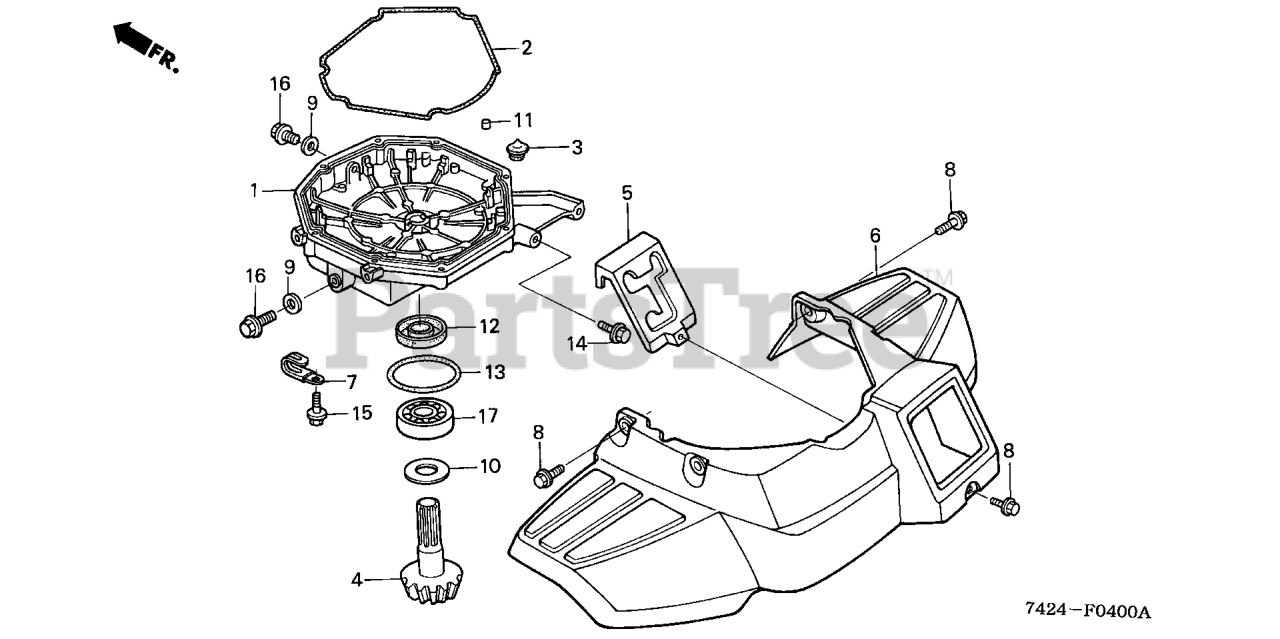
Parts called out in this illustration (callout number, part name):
1	CASE, REDUCTION
3	CAP, TRANS OIL
4	PINION, BEVEL
5	COVER, CHANGE GUIDE
6	FENDER, MAIN *R280* (POWER RED)
7	CLIP, TUBE
8	BOLT, FLANGE (6MM)
9	WASHER (10.5MM)
10	WASHER, BEVEL GEAR
11	PIN, DOWEL (8X12)
12	OIL SEAL (17X32X5)
13	O-RING (41.7X3.5)
14	BOLT, FLANGE (6X14)
15	BOLT, FLANGE (6X45)
16	BOLT, FLANGE (10X16)
17	BEARING, RADIAL BALL (6203)
